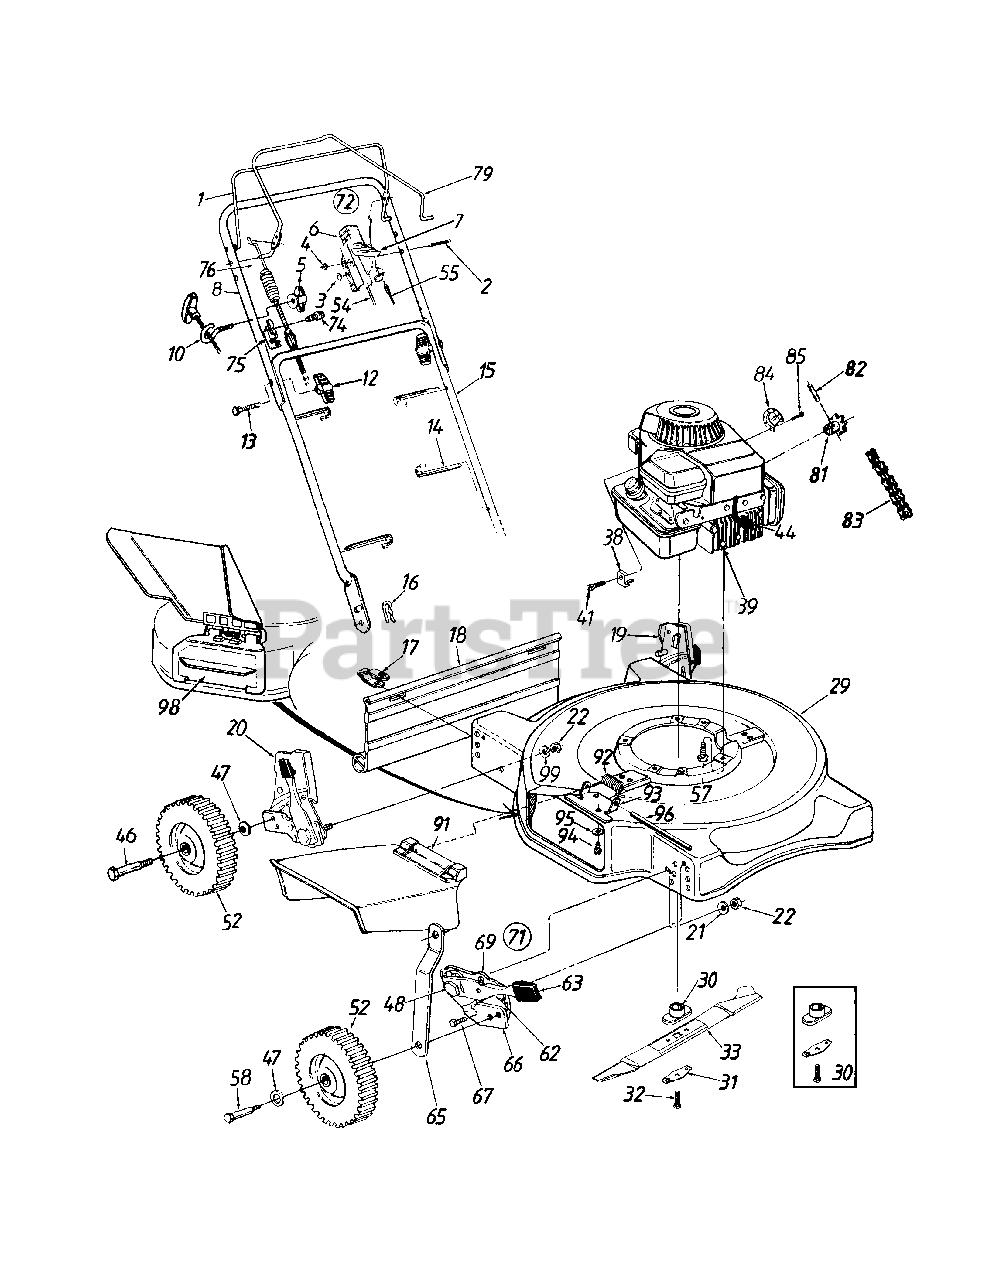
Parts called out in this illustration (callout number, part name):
2	Oval C-Sunk Mach. Scr.
3	Spr. Wash. .66" I.D.
4	Hex L-Nut 1/4-20 Thd.
5	Handle Knob 1/4-20 Thd.
6	Throttle Body
7	Throttle Lever
12	Hand Knob
13	Curved Hd. Bolt 5/16-18 x 2" Lg.
14	Cable Tie
16	Hairpin Cotter
17	Hinge Clip
18	Rear Flap
22	Hex Nut 3/8-16 Thd.
31	Blade Bell Support
32	Hex Bolt 3/8-24 x 1.5" Lg.
33	Blade 22" Std. w/Star
38	Cable Clamp
39	Engine
41	Hex Wash, Hd, Scr, #10-32 x .62"
44	Spark Plug Boot
46	Front Axle Bolt
47	Bell-Wash. .400" I.D. x .88"
48	Shld. Bolt .50" Dia. x .357"
52	Front Wheel Ass'y. Comp.
54	Throttle Control Wire--51"
55	Control Cable--51"
57	Hex L-Wash. Hd. Scr. 3/8-16 x 1.0" Lg.
58	Rear Axle Bolt
62	Spring Lever
63	Spring Lever Knob
67	Hex L-Wash. Hd. AB-Tap Scr. 1/4 x .62" Lg.
69	Index Plate
72	Throttle Box Comp.
74	Hex Wash. AB-Tap Scr. 5/16 x .75" Lg.
75	Cable Brkt.
76	Clutch Cable w/Spring--47"
82	Spring Pin Spir. 3/16" Dia. x 1" Lg.
83	#48 Chain 1/2" Pitch 50 Links (Endless)
84	Exhaust Deflector
85	Hex AB-Tap Scr. #8 x .5" Lg.
91	Chute Deflector Ass'y.
92	Torsion Spring
93	Adapter Plate
94	Hex Self-Tap Scr. 1/4-20 x .5" Lg.
95	Bell-Wash. 1/4" I.D.
96	Hinge Pin
98	Mulching Plug
99	Bell-Wash. .39" I.D. x 1.38" O.D.
